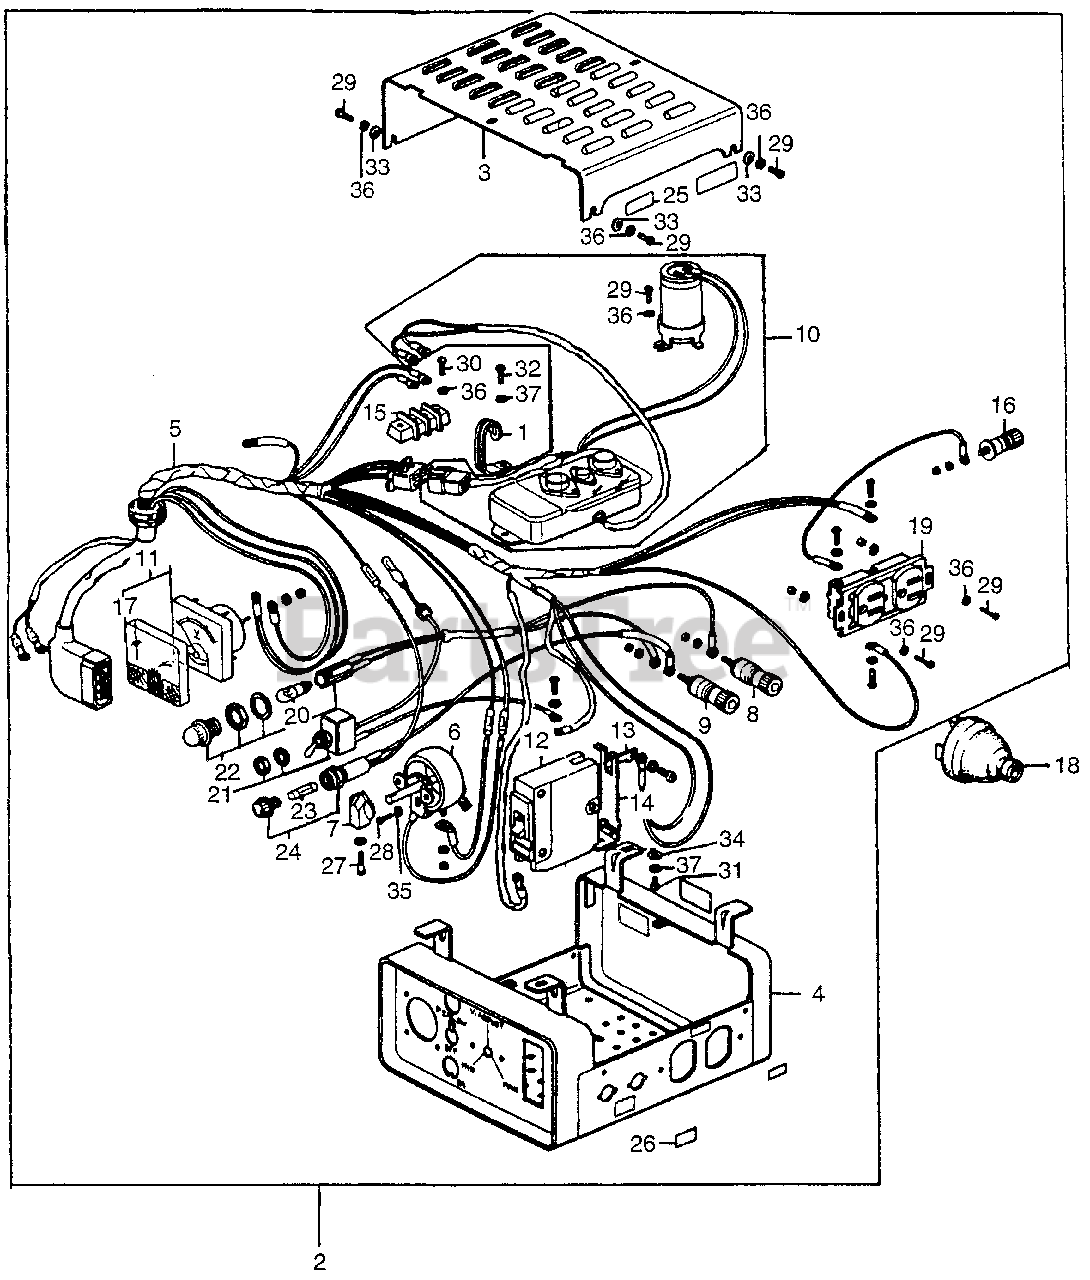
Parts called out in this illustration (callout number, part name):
1	CLAMP B, WIRE
2	BOX ASSY., CONTROL *R8* (BRIGHT RED)
3	COVER, CONTROL BOX (UPPER) *R8* (BRIGHT RED)
4	COVER, CONTROL BOX (LOWER) *R8* (BRIGHT RED)
5	WIRE HARNESS ASSY.
6	RESISTOR, VARIABLE (NOT AVAILABLE)
7	KNOB, ADJUSTING
8	TERMINAL, D.C. OUTPUT (+)
9	TERMINAL, D.C. OUTPUT (-)
10	REGULATOR ASSY., AUTOMATIC VOLTAGE
11	VOLTMETER ASSY. (150V SCALE)
11	VOLTMETER ASSY.
12	BREAKER, CIRCUIT (10A)
13	TERMINAL, BREAKER
14	SUPPORT, BREAKER (NOT AVAILABLE)
15	TERMINAL (2 POLE)
16	TERMINAL ASSY., GROUND (NOT AVAILABLE)
17	LENS, METER (NOT AVAILABLE)
18	PLUG ASSY., RECEPTACLE
19	RECEPTACLE (15A/125V)
20	BULB, DASH (24V-2W)
21	SWITCH ASSY., ENGINE (NOT AVAILABLE)
22	SOCKET ASSY., PILOT LAMP (NOT AVAILABLE)
23	FUSE (15A)
24	HOLDER ASSY., FUSE (NOT AVAILABLE)
25	MARK C, CAUTION (NOT AVAILABLE)
26	MARK B, D.C. OUTPUT (NOT AVAILABLE)
27	BOLT, KNOB (NOT AVAILABLE)
28	SCREW, PAN (3X6)
29	SCREW, PAN (4X6)
30	SCREW, PAN (4X12)
31	SCREW, PAN (5X8)
32	SCREW, PAN (5X10)
33	WASHER, PLAIN (4MM)
34	WASHER, PLAIN (5MM)
35	WASHER, SPRING (3MM)
36	WASHER, SPRING (4MM)
37	WASHER, SPRING (5MM)
